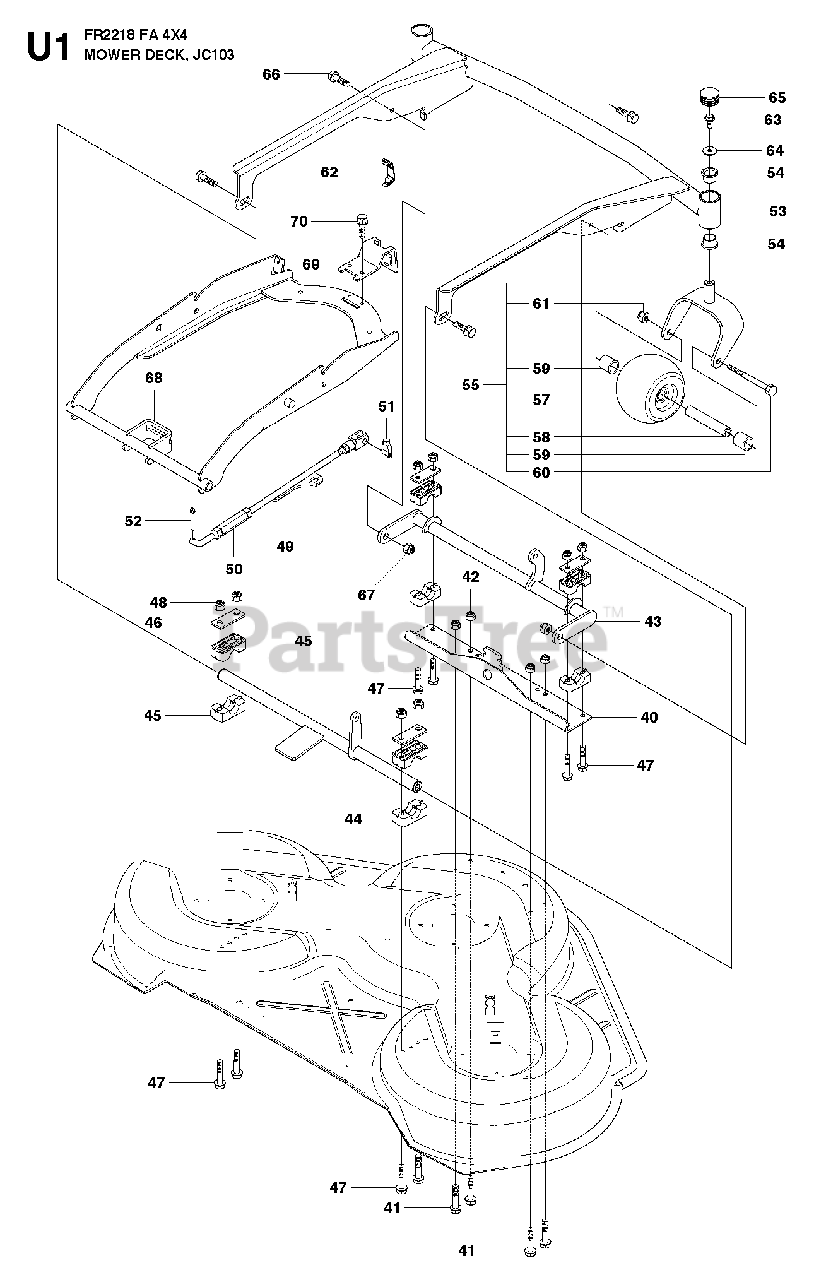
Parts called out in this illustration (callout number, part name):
42	LOCKNUT M8
48	LOCKNUT M8
49	PARALLELL ROD ASSY
50	PARALLEL ROD
51	RETAINER
52	SPLIT PIN
57	DECK ROLLER, FRONT
62	CLIP GRAY
67	LOCKNUT M8
